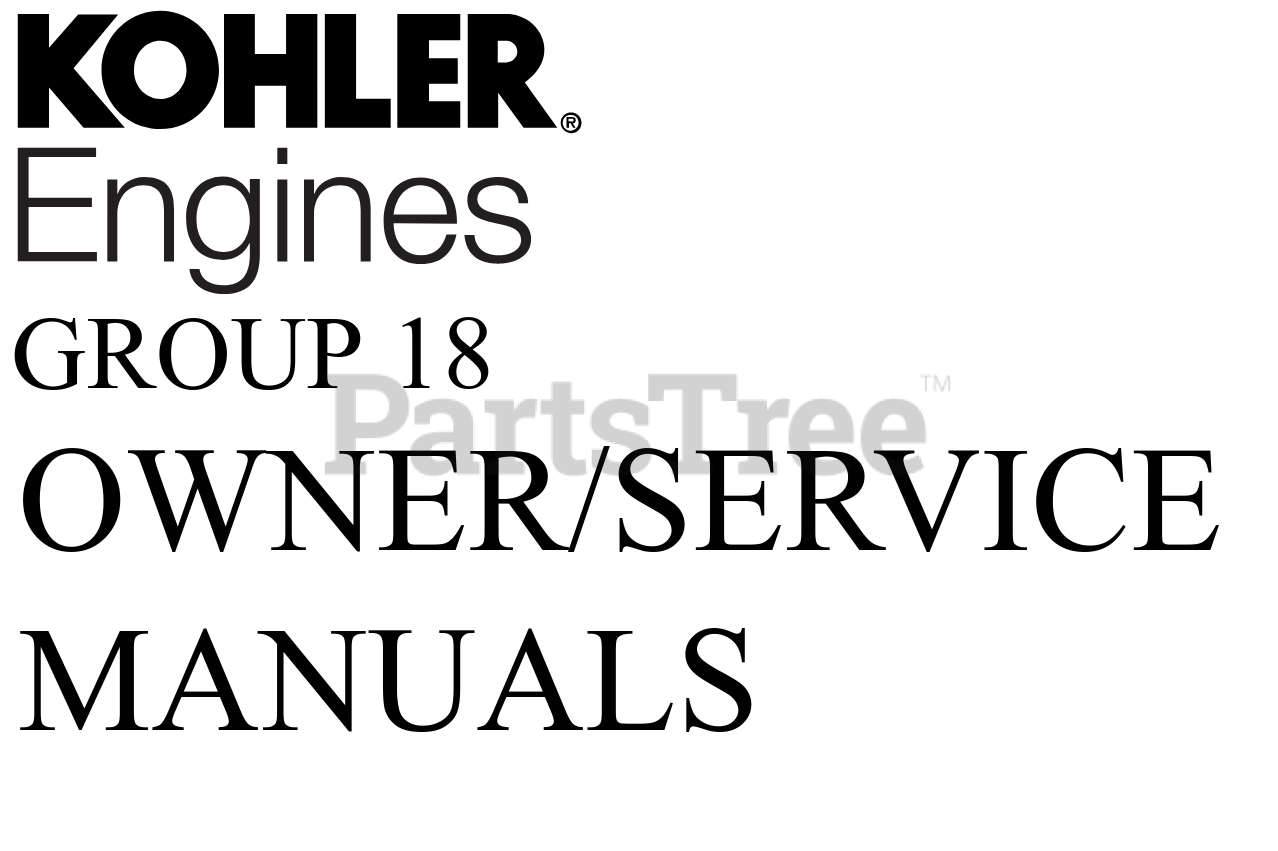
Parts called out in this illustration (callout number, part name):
NI	OM, XT SERIES AMERICAS
NI	OM, XT SERIES WESTERN EUROPE
NI	OM, XT SERIES ROW
NI	OM, XT SERIES EASTERN EUROPE
NI	WARRANTY, 2020-2022 MY XT,XTX,HD SERIES
NI	SM, COURAGE XT-6/XT-7
NI	SM, XT-6/XT-7 COURAGE FRENCH
NI	SM, COURAGE XT ITALIAN
NI	SM, COURAGE XT SPANISH
NI	SM, COURAGE XT CHINESE
NI	SM, XT GERMAN
NI	SM, XT RUSSIAN
NI	SM, XT POLISH
